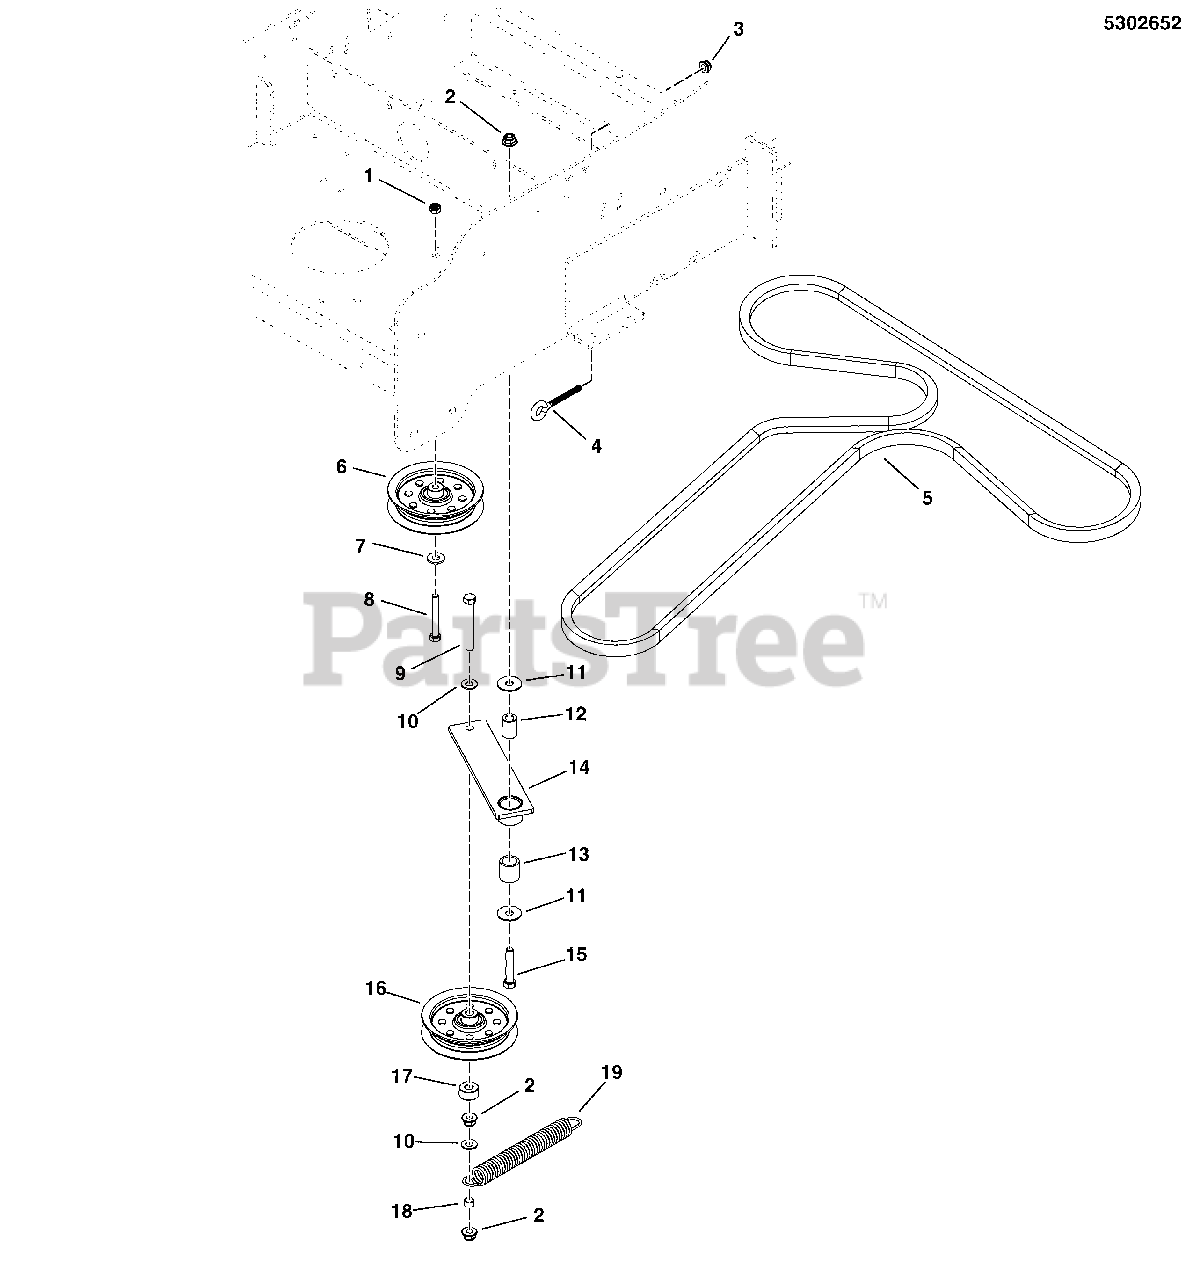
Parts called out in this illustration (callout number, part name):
1	NUT, Hex Nylock, 5/16-18
2	NUT, 3/8-16, Hex Flange Nylock
3	NUT, 5/16-18, Flange Nylock, GR F, Zinc/Clear
4	EYE BOLT,5/16-18 X3.5,2.13THRD,.55EYE,CZ
6	PULLEY, IDLER, STATIONARY
7	WASHER, 5/16" USS
8	BOLT, 5/16-18 X 2-1/2" GD5 YZ
9	BOLT, 3/8-16 X 3 GD5 TFL
10	WASHER, 3/8 SAE
11	WASHER, 3/8" Fender
12	SPACER, .38 X .75 X 1.06, YZ
13	BUSHING, BRASS, 3/4 X 1 X 1
14	WELD, IDLER ARM, SNAPPER PRO - BLK
15	BOLT, 3/8-16 X 2, GD5, YZ
16	PULLEY-IDLER, 4.06OD, .375ID, .75W STL
17	SPACER, .39 X 1.00 X .50, PM, CZ
18	SPACER, .38 X .50 X .27, CZ
19	SPRING, EXTENSION, 1.00
20	BOLT,HEX FLG,SER GD5 3/8-16X2, PATCH,CZ
